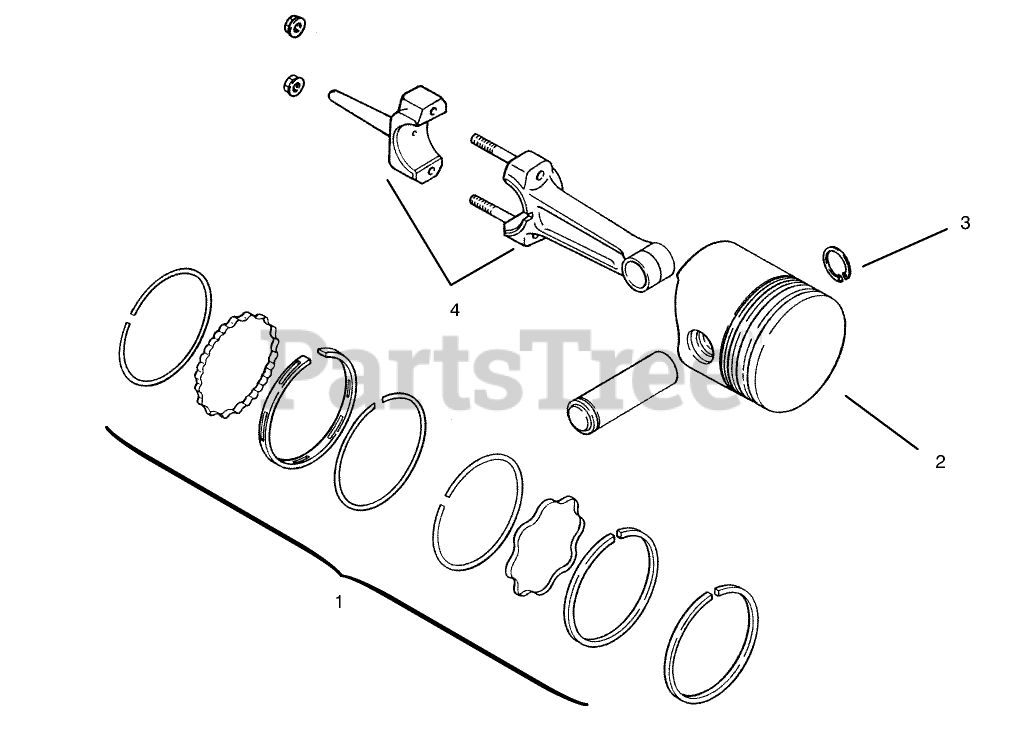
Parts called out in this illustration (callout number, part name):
1	Set-Ring STD .003 14hp
1	Set-Ring .010
1	Set-Ring .020
1	Set-Ring .030
2	Piston-Ring Set STD 14hp
2	Piston-Ring Set .003
2	Piston-Ring Set .010
2	Piston-Ring Set .020
2	Piston-Ring Set .030
3	Retainer
4	Rod-Connecting STD
